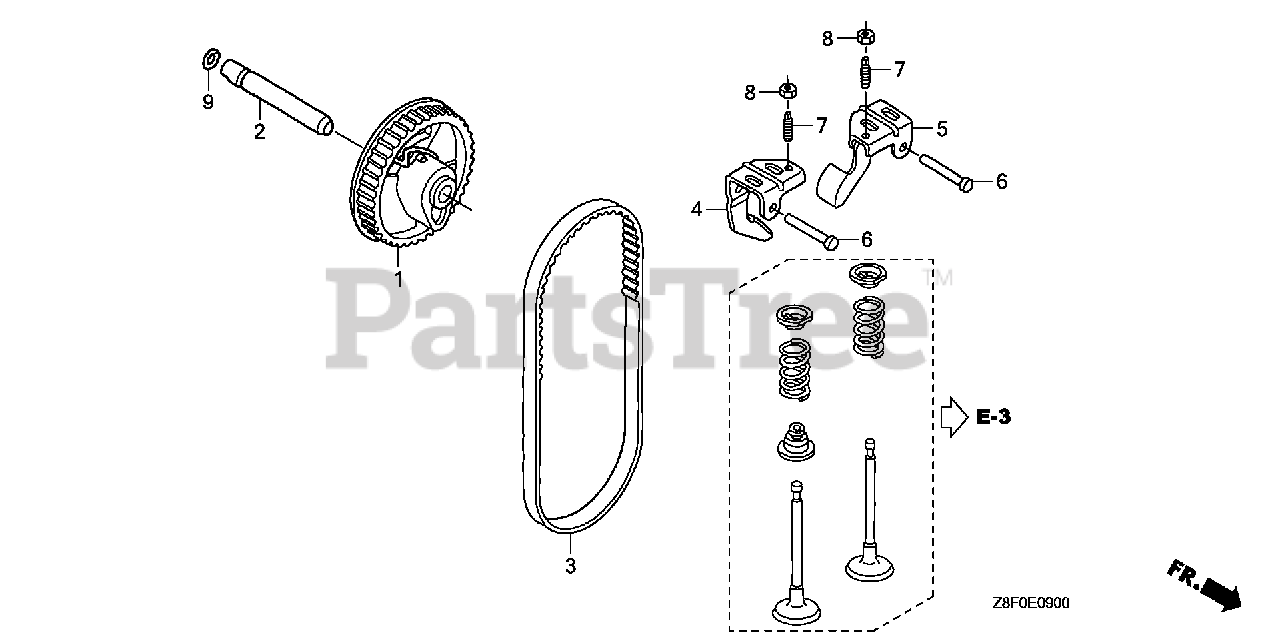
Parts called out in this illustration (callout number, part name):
1	PULLEY, CAMSHAFT
2	SHAFT, CAM PULLEY
3	BELT, TIMING (84HU7 G-200)
3	BELT, TIMING
4	ARM, IN. VALVE ROCKER
5	ARM, EX. VALVE ROCKER
6	SHAFT, ROCKER ARM
7	SCREW, TAPPET ADJ.
8	NUT, TAPPET ADJ.
9	O-RING (6.8X1.9) (ARAI)
